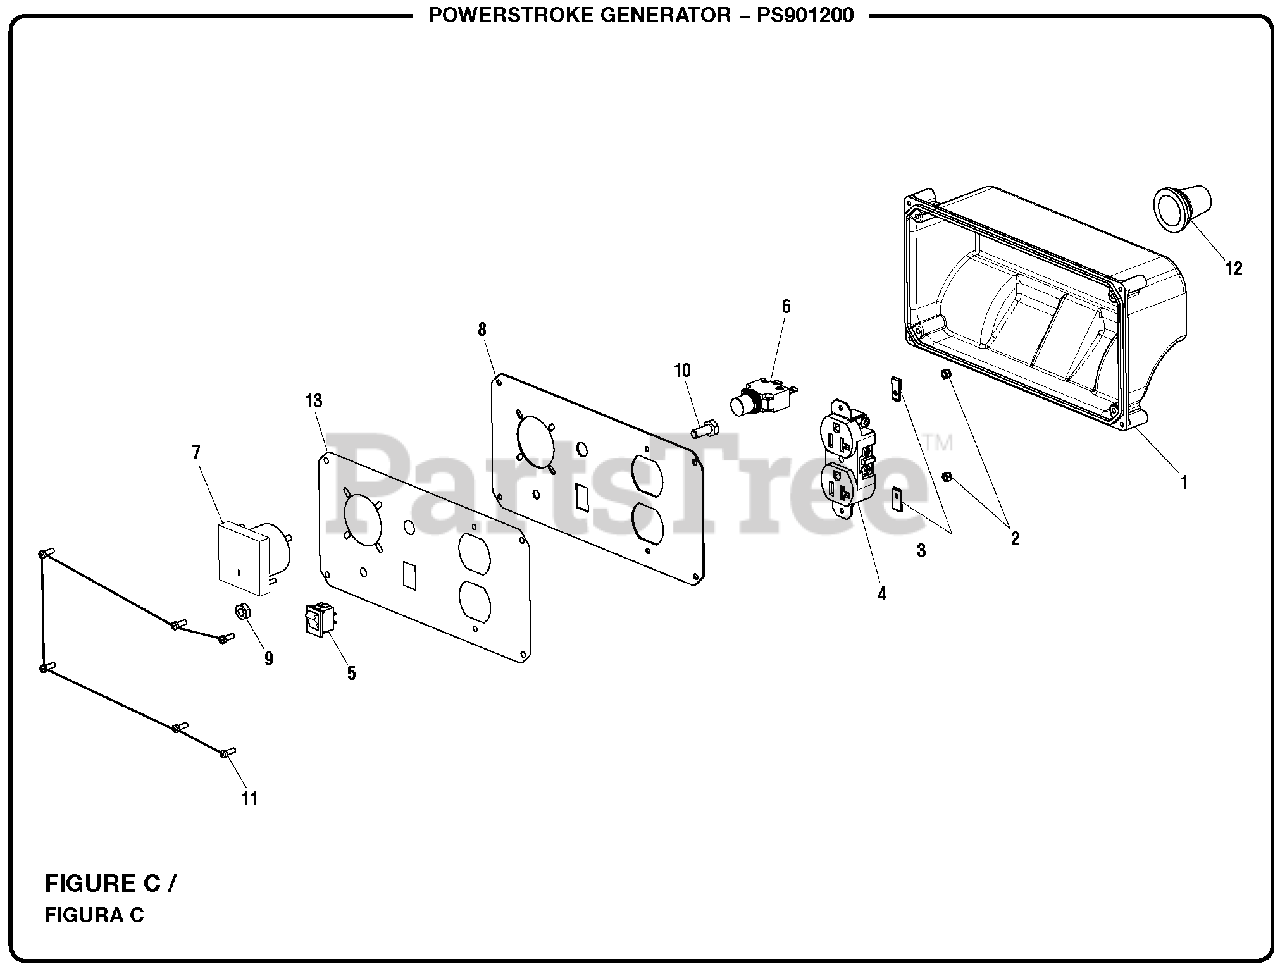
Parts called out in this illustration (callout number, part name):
1	Control Box (Back Panel)
2	Lock Nut (M4)
4	Duplex Receptacle (120 Volt)
5	Stop Switch
6	Circuit Breaker (9 Amp)
7	Analog Voltage Meter
8	Front Panel
9	Hex Nut (M6)
10	Bolt (M6 x 20 mm, Hex Hd.)
11	Bolt (M4 x 10 mm)
12	Rubber Sleeve
13	Control Panel Label
